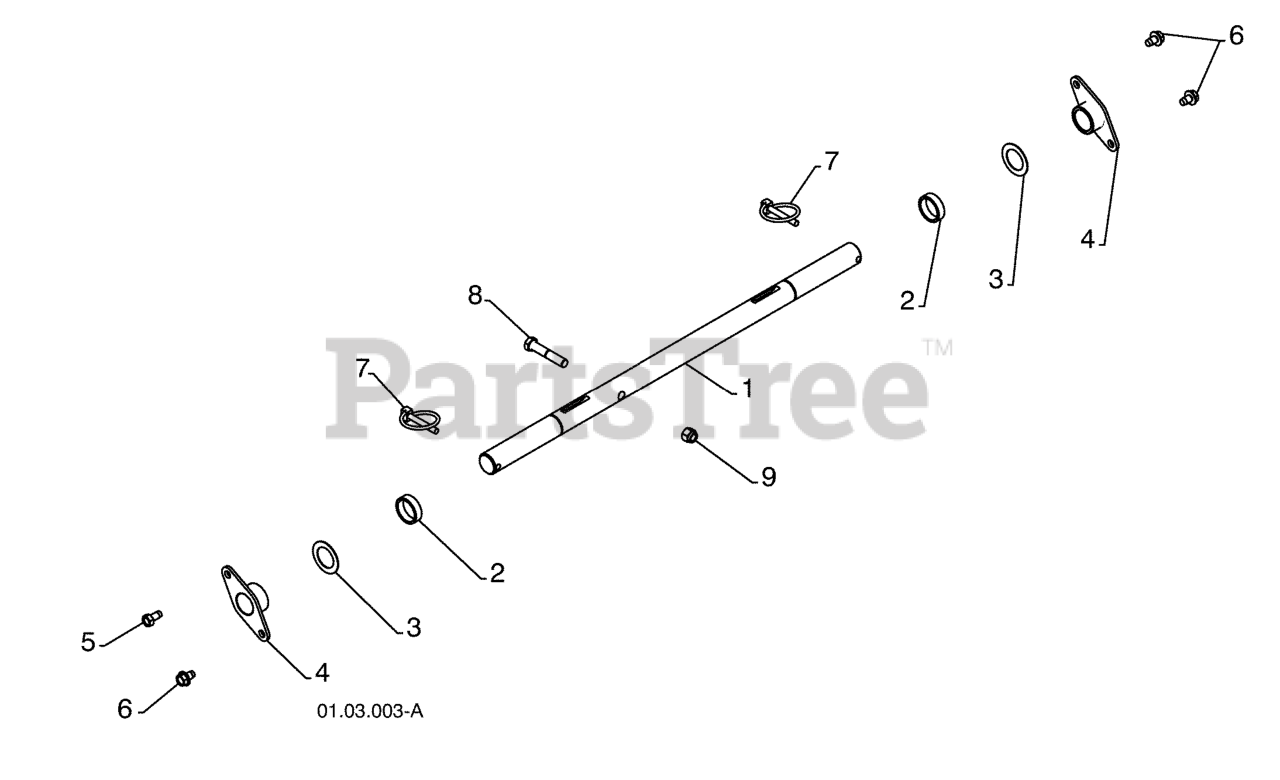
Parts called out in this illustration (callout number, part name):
1	SHAFT.AXLE.POWER.STEERING.HYD
2	SPACER.AXLE.RH
3	WASHER TRUST 1"
4	BEARING, AXLE
6	BOLT 5/16-18 X .500
7	PIN KLIK, 1/4
8	CAP.SCREW.HEX.HD.3/8-16
9	NUT
